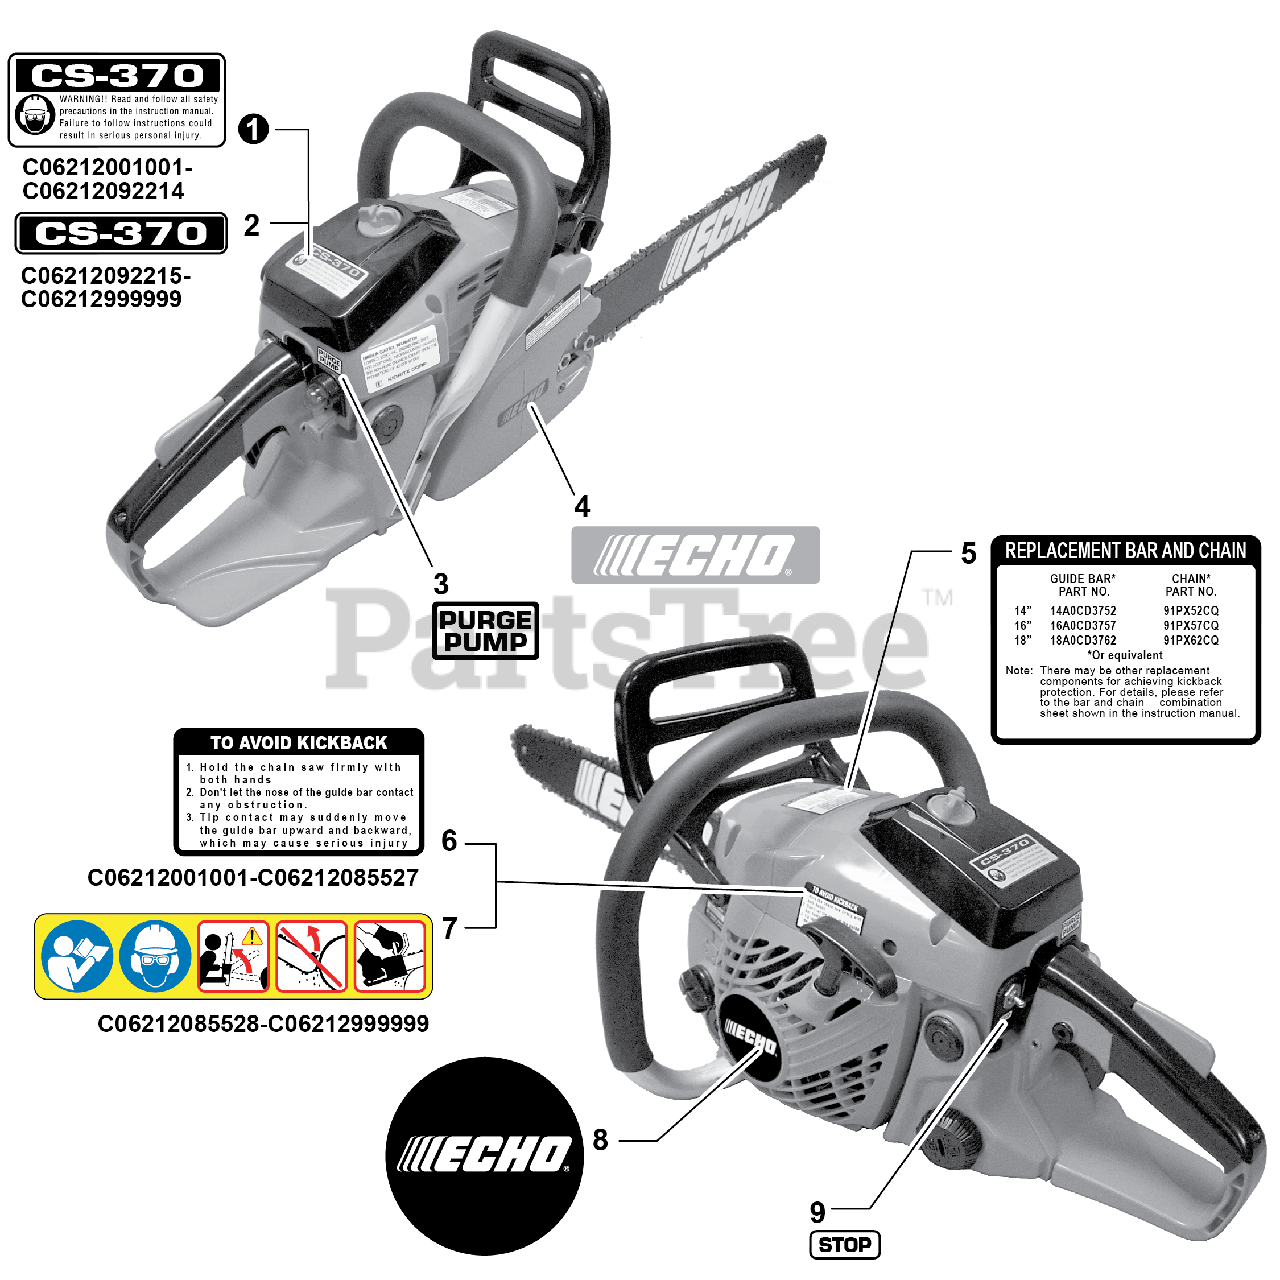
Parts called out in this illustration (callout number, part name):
1	LABEL - MODEL CS-370
2	LABEL - MODEL CS-370
3	LABEL, PURGE PUMP
4	LABEL, ECHO
5	LABEL, BAR & CHAIN
6	LABEL, UL - KICK BACK
7	LABEL, CAUTION
8	LABEL, ECHO
9	LABEL, STOP
